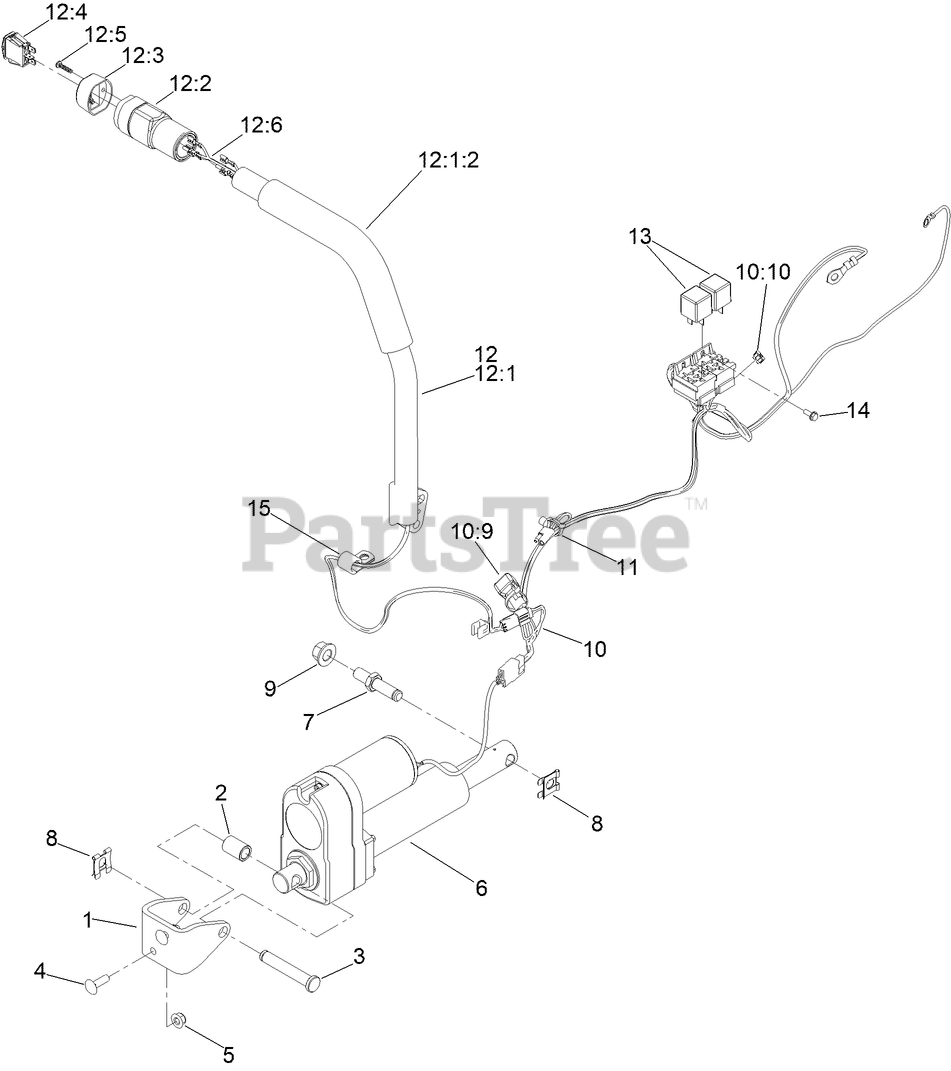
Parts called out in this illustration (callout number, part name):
1	CYL MOUNT PLATE
2	SPACER-ALUMINUM
3	PIN-CLEVIS
4	SCREW-CARR
5	NUT-HF, NI
6	ACTUATOR-LINEAR
7	PIN-PIVOT, ACTUATOR
8	CLIP-PIN
9	NUT-LOCK
10	HARNESS-WIRE, DECK LIFT
10:10	FUSE-BLADE, 20 AMP
11	CLIP-TIE
12	HANDLE ASM-LH
12:1	HANDLE ASM-LH
12:1:2	GRIP-CONTROL, LEVER
12:2	CASE ASM
12:3	CAP-SWITCH
12:4	Air Cleaner Element
12:5	SCREW-PPH
12:6	HARNESS-WIRE, HANDLE
14	SCREW-TAPTITE
15	R-CLAMP
